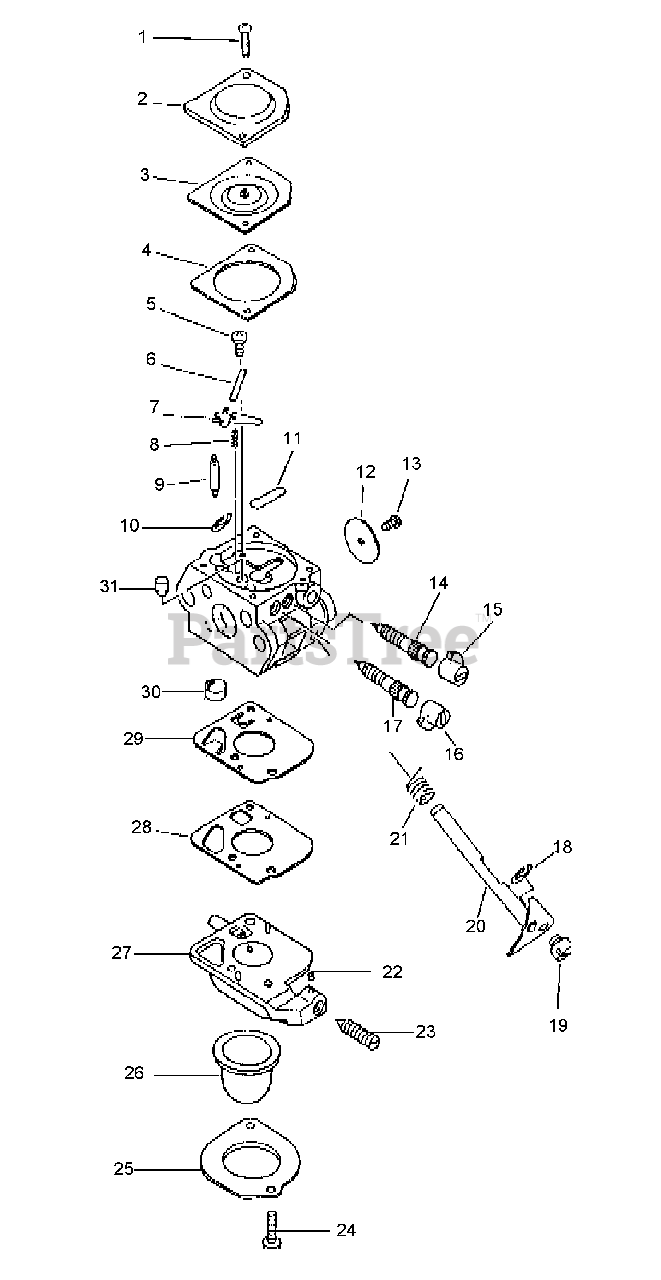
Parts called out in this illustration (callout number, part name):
2	COVER, METERING
3	DIAPHRAGM, METERING
4	GASKET, METERING
5	SCREW, METERING LEVER PIN
6	PIN, METERING LEVER
7	LEVER, METERING
8	SPRING, METERING LEVER
9	VALVE, NEEDLE
10	RING, RETAINING
11	PLUG, WELCH
12	VALVE, THROTTLE
14	NEEDLE - LOW SPEED
15	CAP, LIMITER
16	CAP, LIMITER
17	NEEDLE - HIGH SPEED
18	RING, RETAINING
20	SHAFT, THROTTLE
21	SPRING, RETURN
22	PIECE, FRICTION
23	SCREW, IDLE ADJUST
24	SCREW, RETAINER
25	RETAINER, PURGE BULB
26	BULB, PURGE
27	BASE, PURGE
28	GASKET, PUMP
29	DIAPHRAGM, PUMP
30	STRAINER
31	NOZZLE, CHECK VALVE
